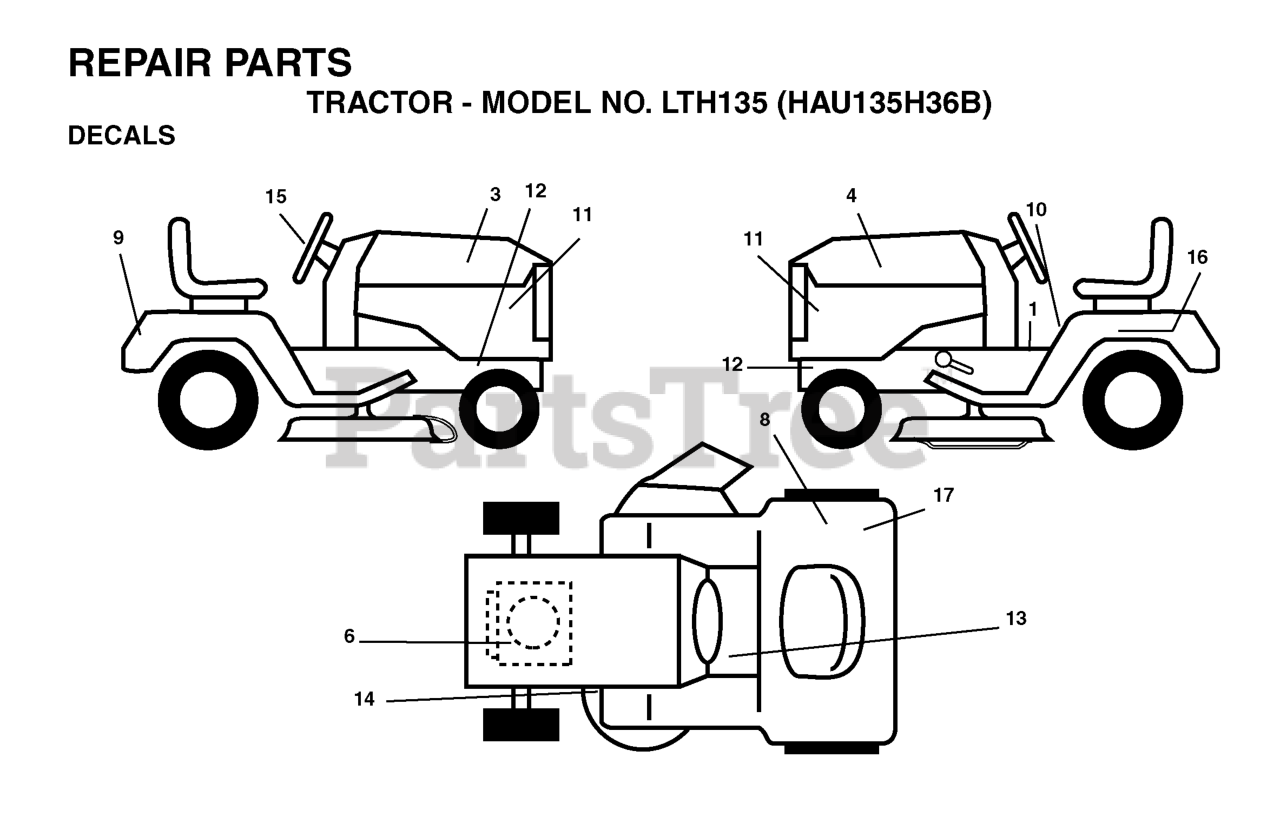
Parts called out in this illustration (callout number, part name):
1	DECAL READ OWNER'S MAN SYMS
8	DECAL
9	DECAL FENDER HUSQ
10	DECAL PARK BRAKE
11	DECAL PNL SIDE
13	DECAL
14	DECAL V-BELT SCHEMATIC
15	DECAL.WHEEL.STEERING.HUSQ.PERM
16	DECAL BTRY SYMBOLS
17	DECAL.INTERNATIONL.CUTFINGER
